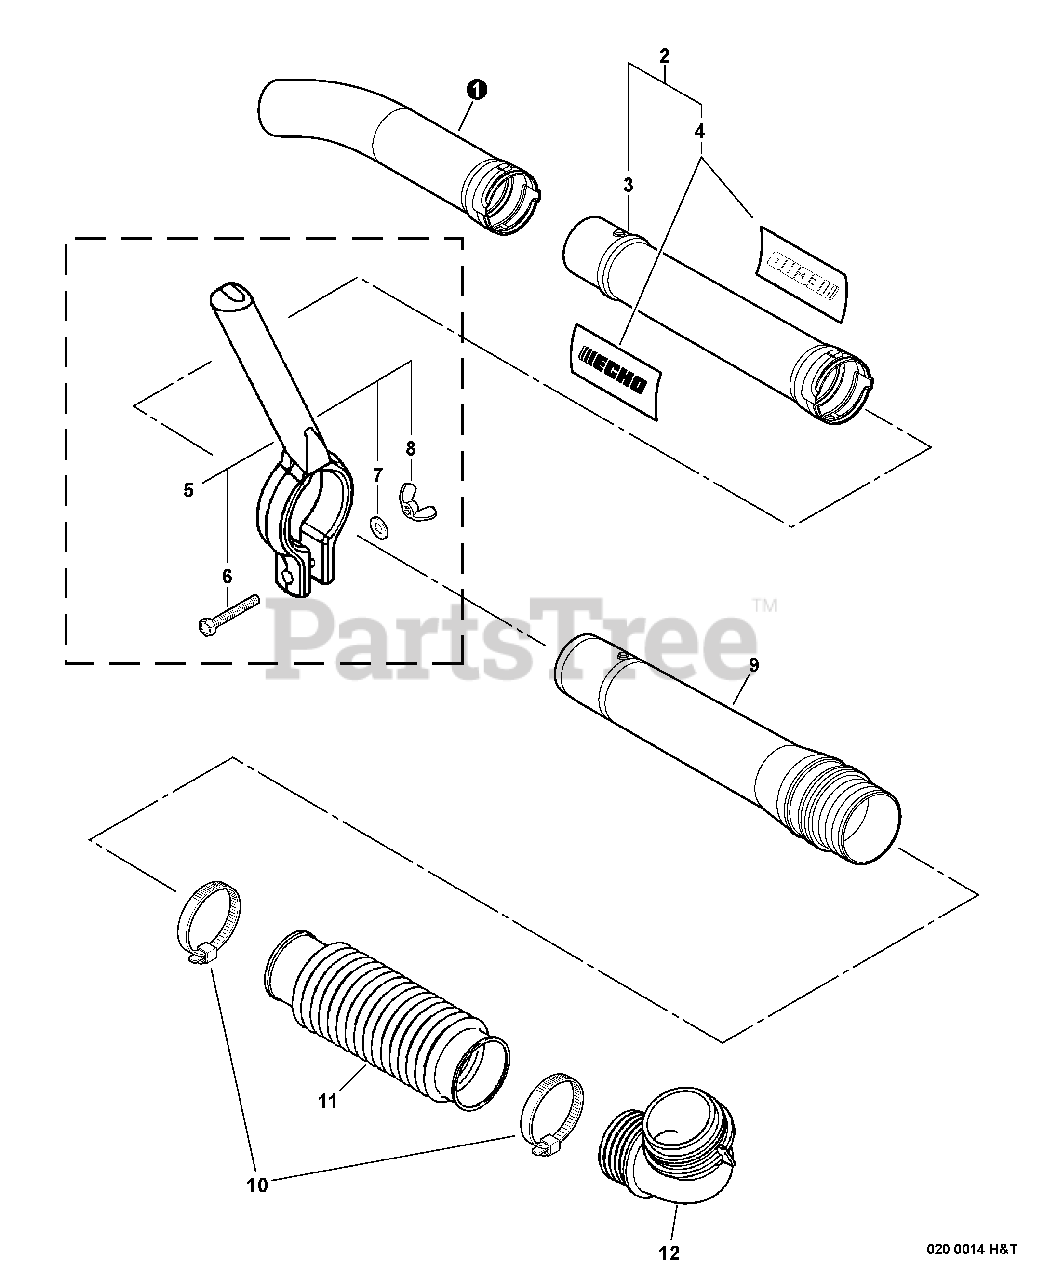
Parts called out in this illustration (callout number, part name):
1	TUBE, BLOWER - CURVED
2	BLOWER TUBE KIT - STRAIGHT
3	TUBE, BLOWER - STRAIGHT
4	LABEL - ECHO
5	HANDLE ASSY
6	BOLT - 6X45
7	WASHER - 6
8	WINGNUT - 6
9	TUBE, BLOWER - SWIVEL
10	CLAMP, HOSE
11	TUBE, BLOWER - FLEXIBLE
12	TUBE, BLOWER - ELBOW
